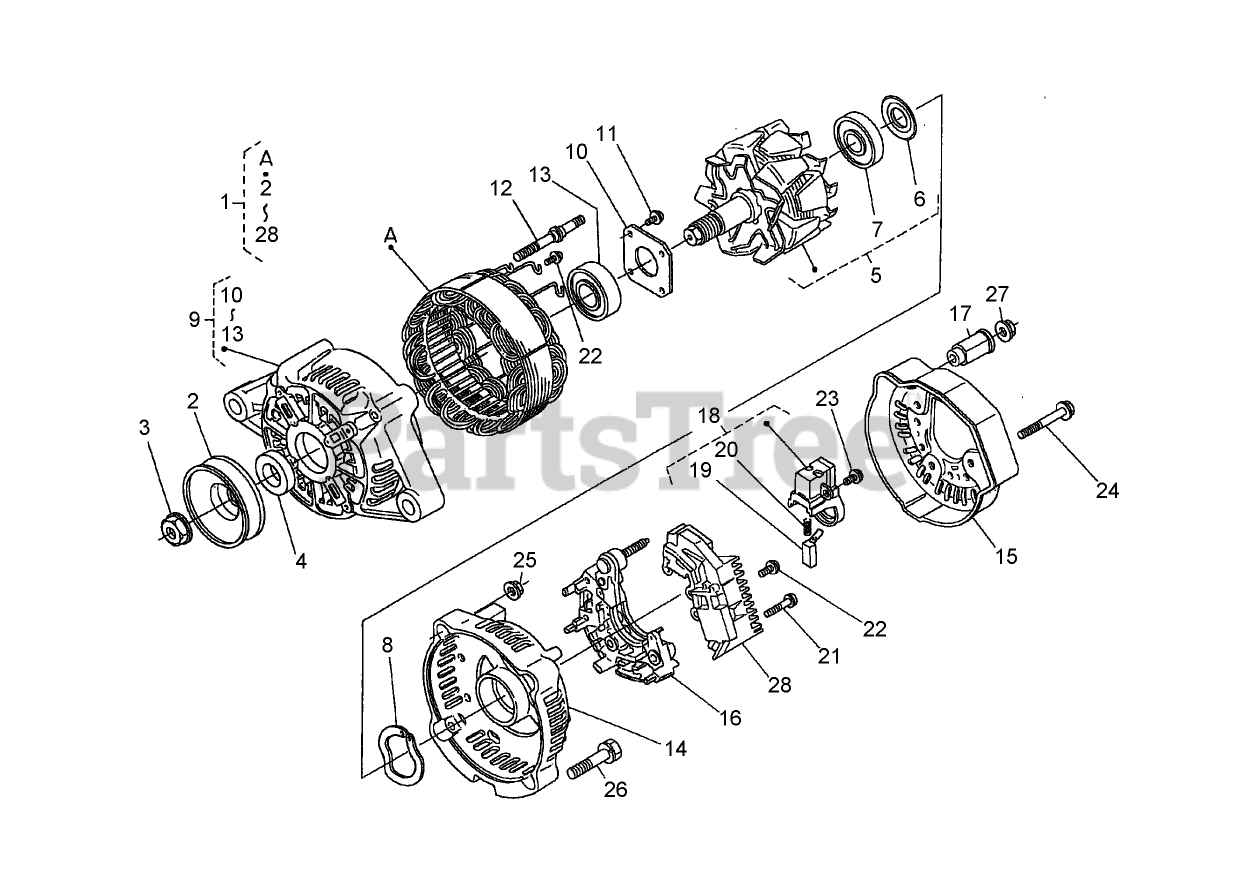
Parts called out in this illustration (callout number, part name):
1	ALTERNATOR ASM
2	PULLEY-DYNAMO
4	COLLAR
5	Rotor ASM
6	COVER-BEARING
7	Bearing-Ball
8	WASHER-THRUST
9	Drive End Frame ASM
10	PLATE-RETAINER
11	SCREW-HEAD, ROUND
12	BOLT-THROUGH
13	Bearing-Ball
14	FRAME-END
15	Cover-End
16	RECTIFIER ASM
17	BUSHING-INSULATION
18	Brush Holder ASM
19	BRUSH
20	SPRING-BRUSH
21	SCREW-HEAD, ROUND
22	SCREW-HEAD, ROUND
23	SCREW-HEAD, ROUND
28	REGULATOR ASM
